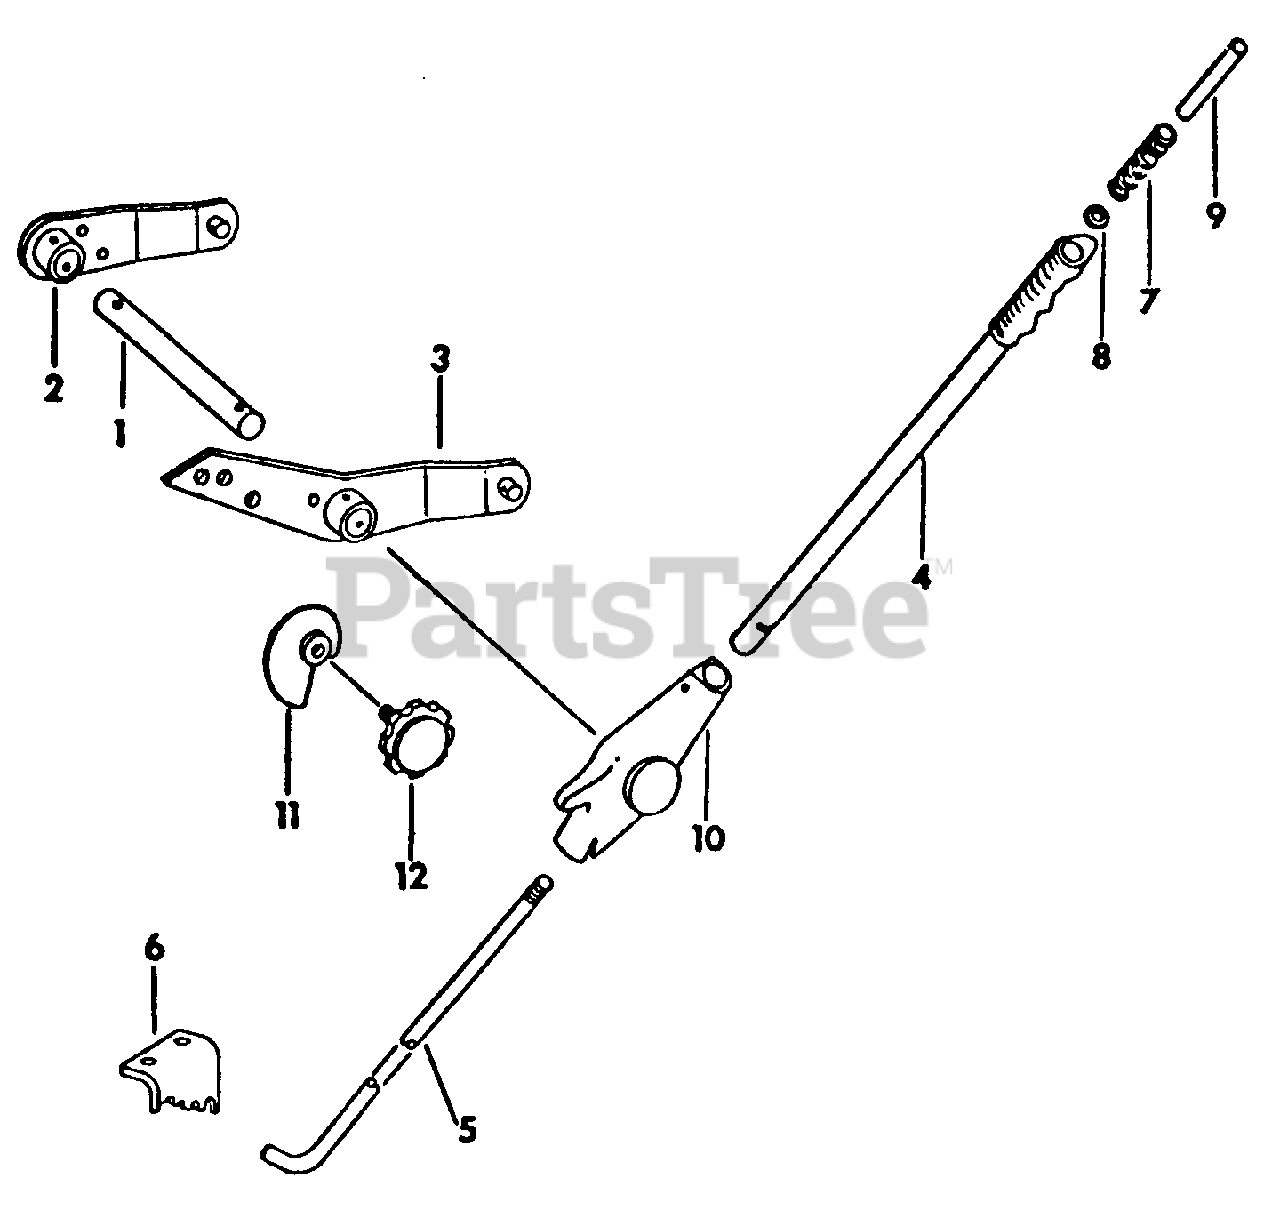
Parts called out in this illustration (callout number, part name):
2	Arm Assy, Lift LH
3	Arm Assy, Lift RH
4	Handle Assy, Lift
5	Rod Assy, Handle Release
6	Ratchet, Lift Handle
7	Spring, Rod Return
8	Retainer, Spring
9	Pin, Release Rod
10	Hub, Lift Handle
11	Cam Assy, Lift Handle Stop
12	Knob, Torque
